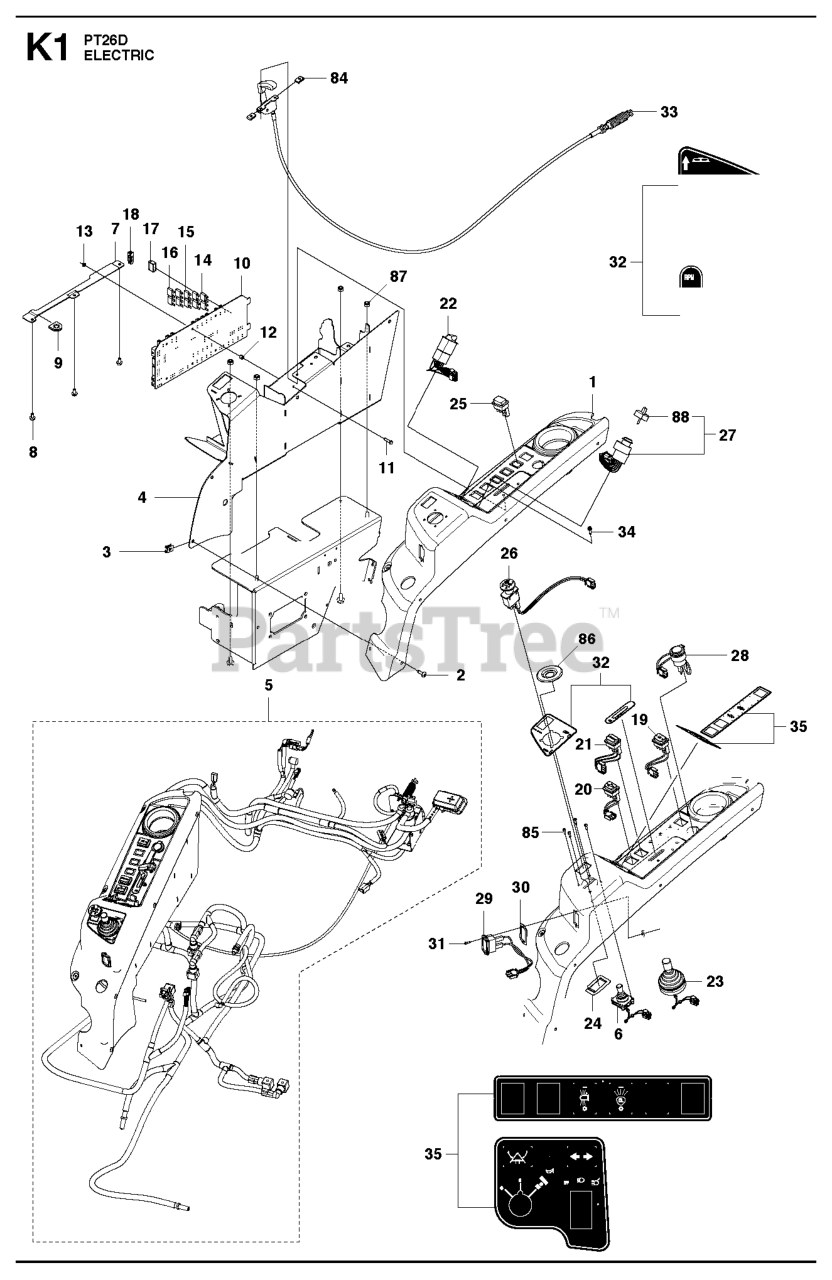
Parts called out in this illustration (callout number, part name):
8	SCREW EHHFM
11	SCREW M6S 5X20
13	LOCKNUT M5
17	COVER FUSE HOLDER
33	THROTTLE HANDLE ASSY
87	LOCKNUT M8
